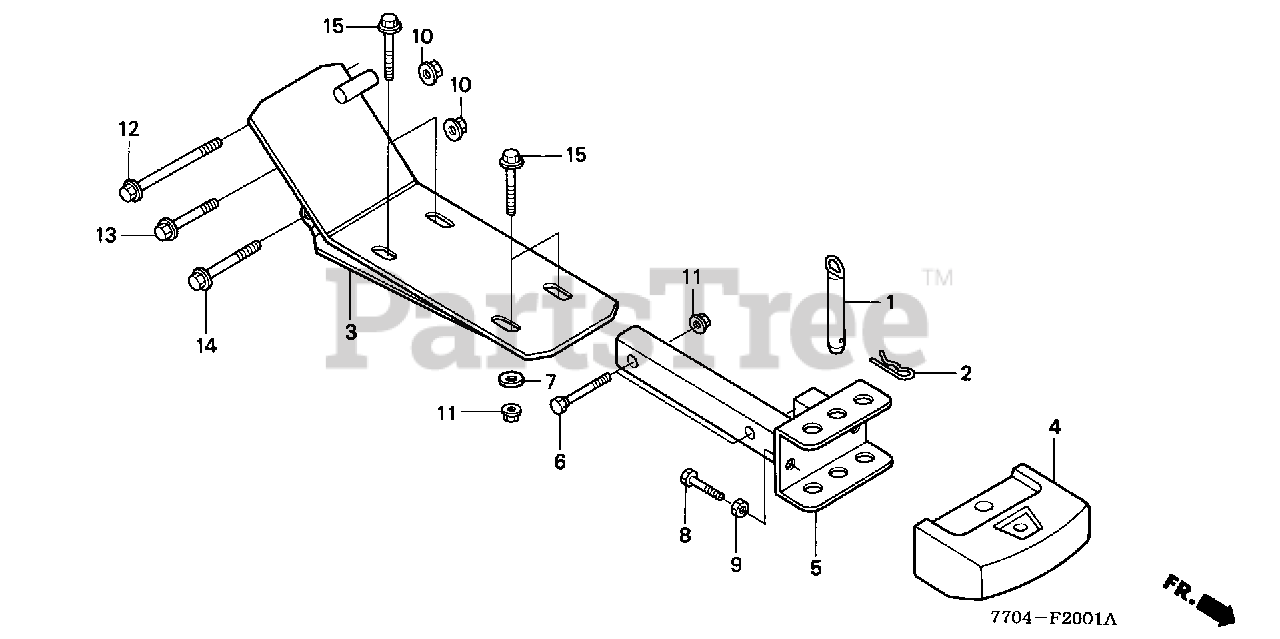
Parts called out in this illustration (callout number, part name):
1	PIN, HITCH
2	PIN, LOCK
3	BED, ENGINE
4	WEIGHT, FR. (8KG) *R280* (POWER RED)
5	HITCH, FR.
6	BOLT, HITCH
7	WASHER, EX. MANIFOLD
8	BOLT, HEX. (8X32)
9	NUT, HEX. (8MM)
10	NUT, FLANGE (8MM)
11	NUT, FLANGE (10MM)
12	BOLT, FLANGE (8X80)
13	BOLT, FLANGE (8X40)
14	BOLT, FLANGE (8X55)
15	BOLT, FLANGE (10X45)
